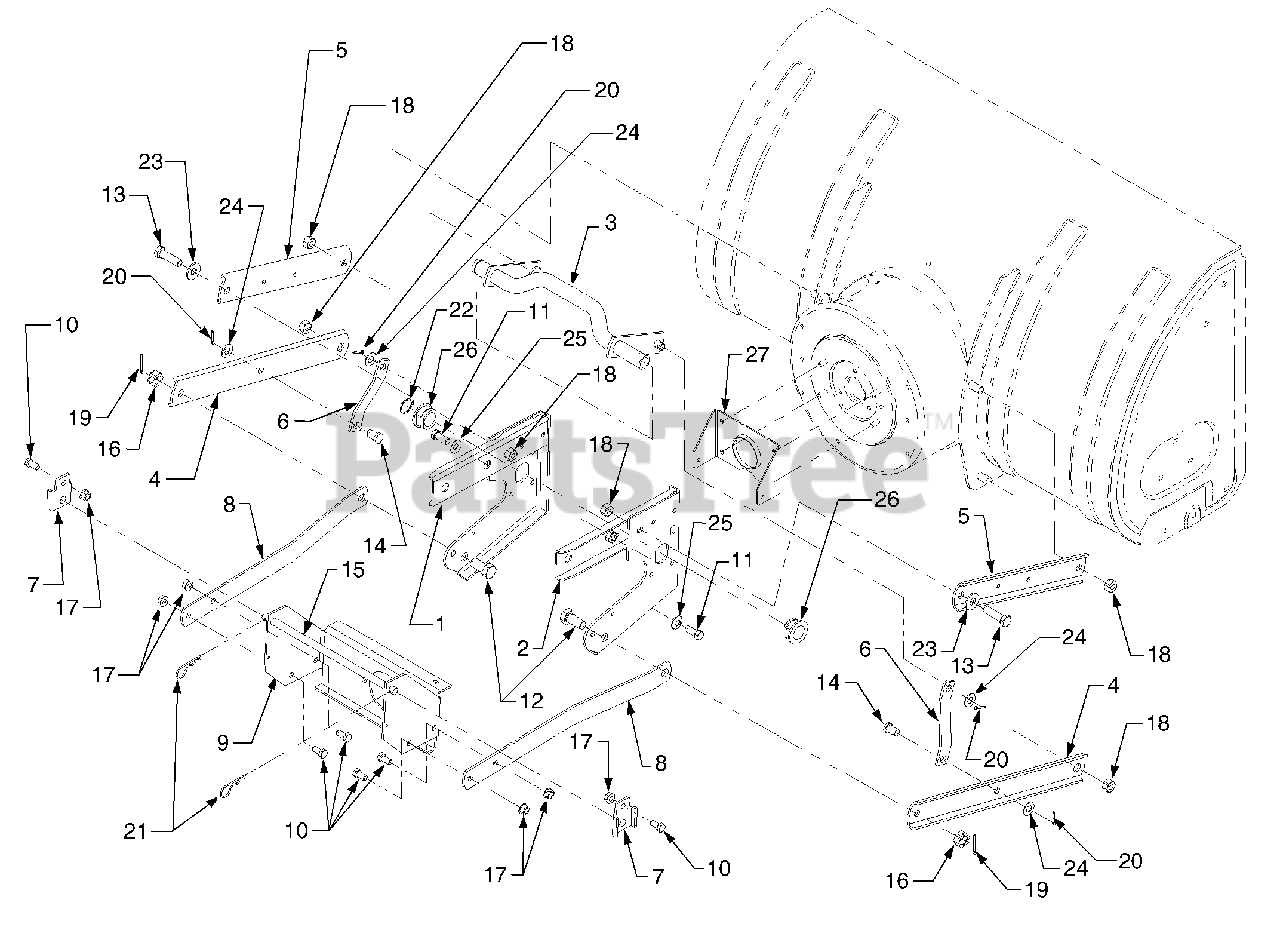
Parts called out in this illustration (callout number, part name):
1	Hitch Plate, RH
2	Hitch Plate, LH
3	Tube Assembly, Lift
4	Link, Lower
5	Link, Upper
6	Link, Lift
7	Bracket, Frame Mounting
8	Arm, Subframe
9	Bracket, Gearbox Mounting
10	Screw, Hex Cap, 3/8-16 x .75 GR5
11	Screw, Hex Cap, 7/16-14 x 1.0 GR5
12	Screw, Hex Cap, 5/8-18 x 1.31 GR5
13	Screw, Hex Cap, 1/2-13 x 1.75 GR5
14	Pin, Clevis, .5 x .78 Lg
15	Rod, .5 x 12.5 Lg
16	Nut, Hex Slotted, 5/8-18
17	Nut, Hex Flange Lock, 3/8-16
18	Nut, Hex Center Lock, 1/2-13
19	Pin, Cotter, 1/8 x 1.25
20	Pin, Cotter, 1/8 x .75
21	Pin, Internal Cotter
22	Ring, Snap, 1.0 Dia. Shaft
23	Washer, Flat, .531 x 1.25 x .10
24	Washer, Flat, .510 x 1.0 x .062
25	Washer, Bell, .45 x 1.0 x .062
26	Bearing, Flange w/Flats
27	Bracket, Box Mounting
